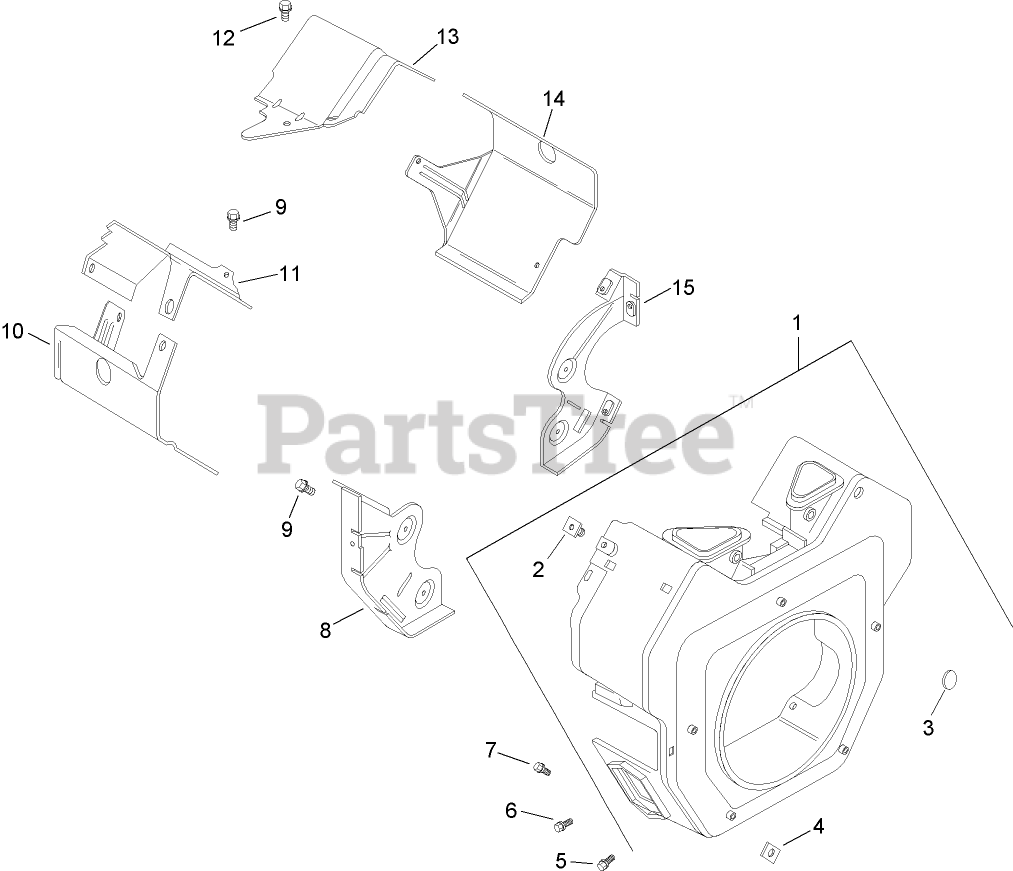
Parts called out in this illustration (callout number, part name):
1	Blower Housing ASM (Includes 2-4)
2	Nut-Plastic
3	PLUG-BUTTON (9/16)
4	NUT-PLASTIC
5	Screw-Hex Flange, Heavy (M5x0.8x16)
6	SCREW-FLANGE, THREAD FORMING (M5X0.8X16)
7	SCREW-FLANGE, THREAD FORMING (M5X.8X20)
8	Plate-Backing (No. 2 Side)
9	SCREW-FLANGE, THREAD FORMING (M6X1.0X16)
10	Baffle-Barrel, Cylinder (No. 2 Side)
11	BAFFLE-VALLEY (No. 2 SIDE)
12	SCREW-HHFTF (M5X.80X10)
13	BAFFLE-VALLEY (No. 1 SIDE)
14	Baffle-Barrel, Cylinder (No. 1 Side)
15	Plate-Backing (No. 1 Side)
